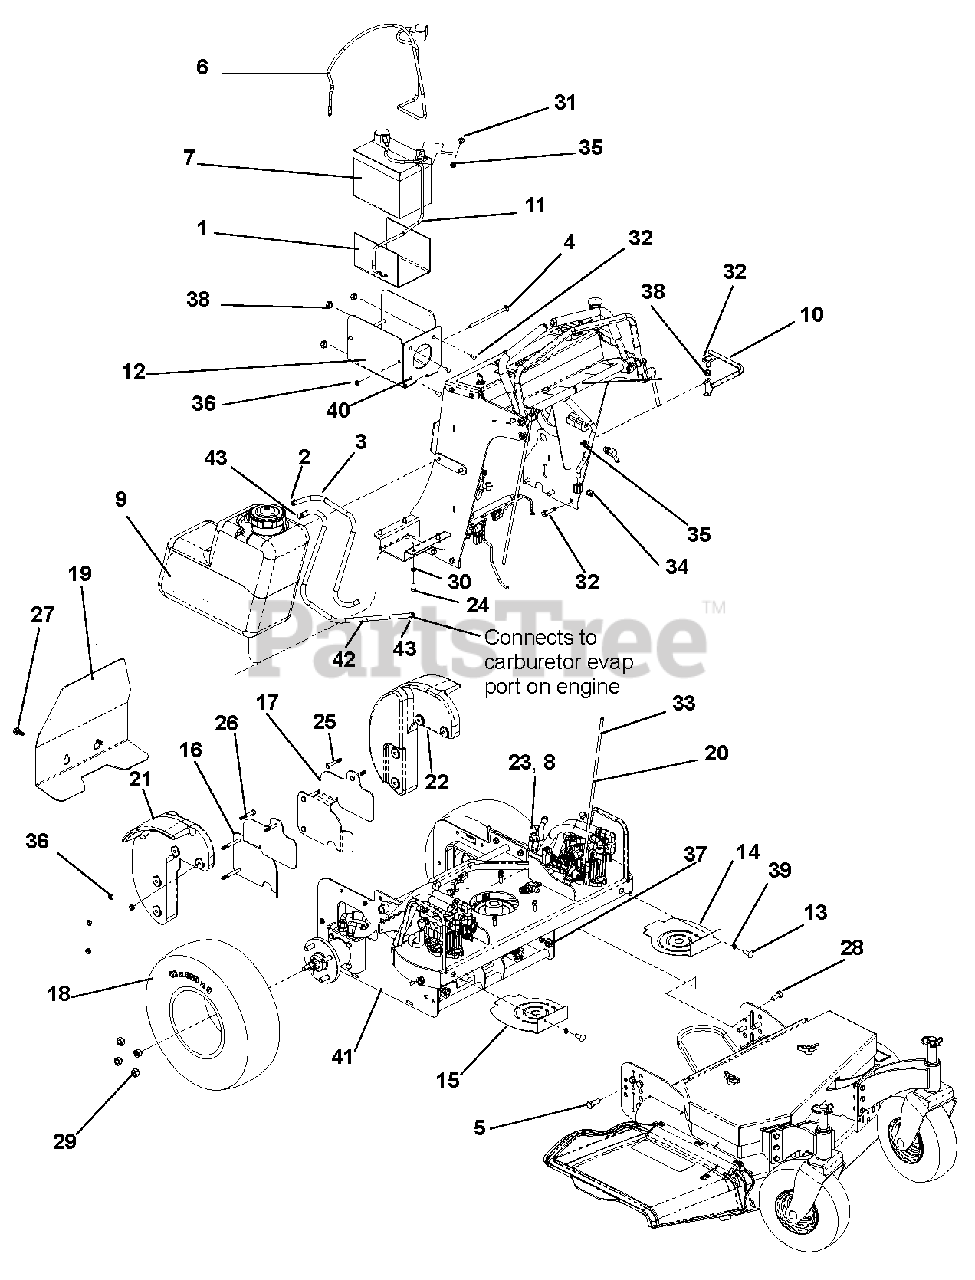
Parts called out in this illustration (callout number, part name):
1	Pad, Battery Insulator
2	Clamp, Hose (Red) #
3	Hose, 1/4" Id Low Perm Fuel 50
4	Bolt, Round Head Square Neck, 5/16-18 x 6"
5	Bolt, .50 x 1.06 x .375-16 Sld 5 Y
6	Cable, Battery Starter - 48"
7	Battery, 12V-U1-CCA 270 min
8	Pin, Clevis Spg 3/8" Yoke Spec Y
9	Tank, Fuel
10	Weldment, Reservior Guard
11	Cable, Battery - 25" Ground
12	Console Battery Bracket, w/Decal
13	Bolt, .25-20 x .750 Hex 5 Y
14	Shield, LH Pump
15	Shield, RH Pump
16	Shield, RH Motor w/Decal
17	Shield, LH Motor w/Decal
18	Assembly, Tire/Wheel 18/6.5 x 8 Slvr
19	Shield, Engine w/Decal
20	Rod, Control 5/16 x 22.75 Y
21	RH Cast Weight Machined
22	LH Cast Weight Machined
23	Clevis, .38-24 Adjustment
24	Bolt, Hex .25-20 x .75 Grade 5
25	Bolt, Hex .31-18 x .75 Grade 5
26	Bolt, .312-18 x 3.00 Hex 5 Y
27	Bolt, .38-16 x 1.00 Fgh 8 Y
28	Bolt, Hex .50-13 x 1.25 Grade 5
29	Nut, .50-20 Lug C
30	Washer, .313 Med Sprg Lock Y
31	Bolt, .25-20 x .625 Wsh Y
32	Bolt, Round Head Square Neck .38-16 x 1.00 G 5
33	Nut, Hex .312-24
34	Nut, Flange .375-16
35	Nut, Locking-Flange .250-20
36	Nut, Locking-Nylon .312-18
37	Nut, Spin Lock-Flange .50-13
38	Nut, Locking-Nylon .38-16
39	Washer, .313 Medium Spring Lock Y
40	Trim, Rubber Edge 2"
41	Power Unit 19 Narrow (see page 12)
42	Hose, Fuel Low-Perm Bulk Gas .188
43	Clamp, Hose Spring .188
